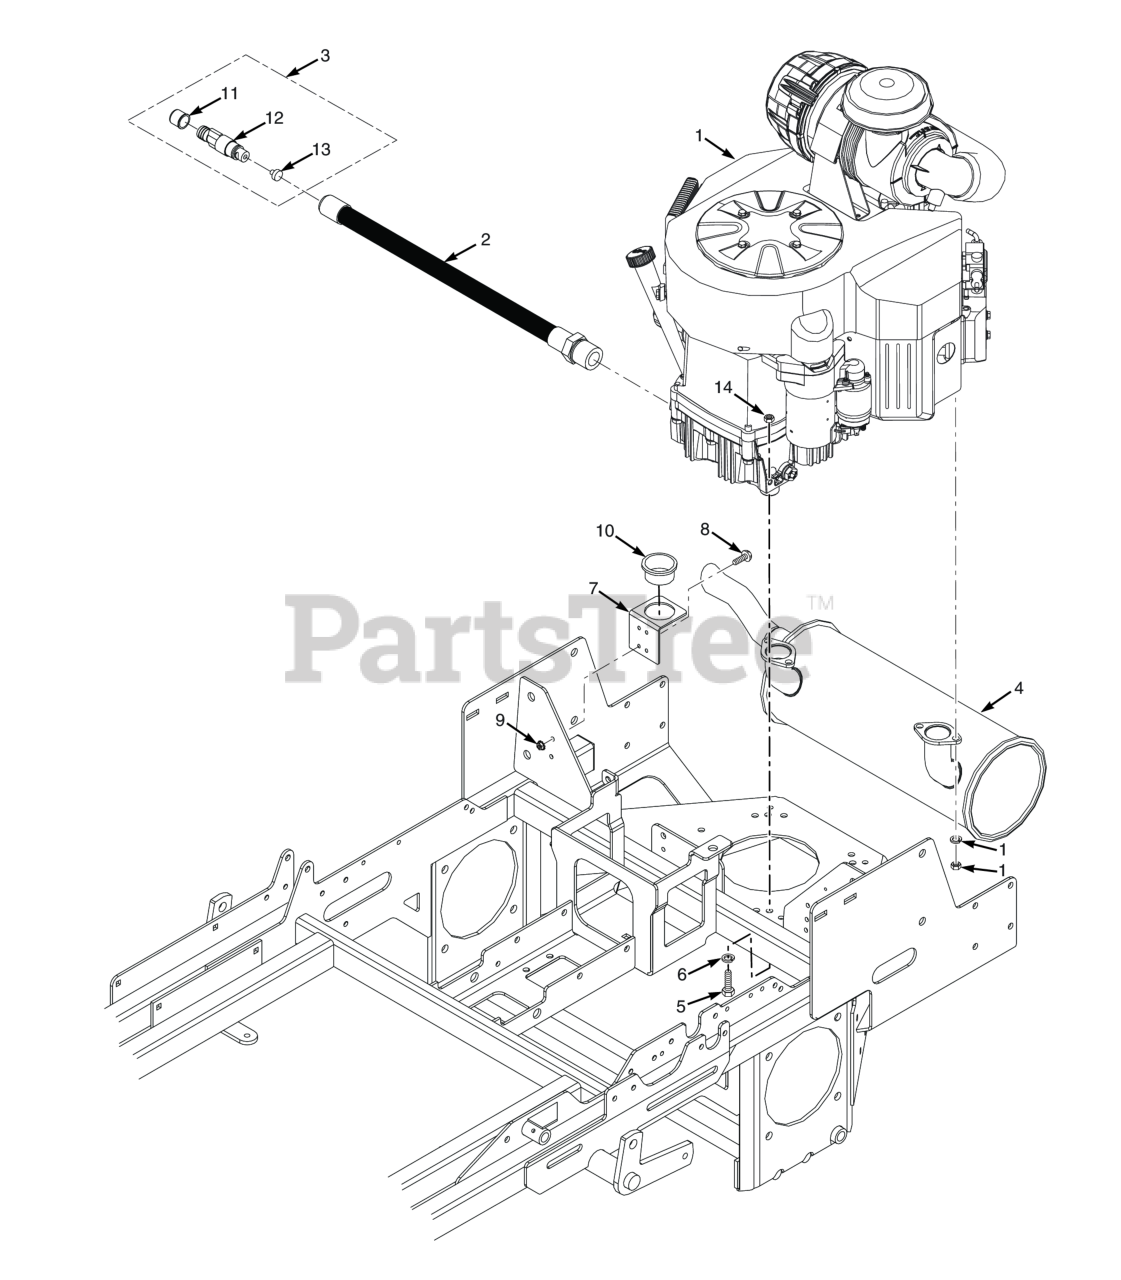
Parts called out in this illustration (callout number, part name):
1	Engine, Briggs & Stratton 37 BV-EFI (61E8770002J1)
2	Hose Assembly, Engine Oil Drain - Kawasaki FS/FX
3	Valve Assembly, Oil Drain
4	Muffler, Kawasaki - FX921
5	Bolt, Hex Head 3/8-16 x 1-1/4", Kawasaki FX / FT & FT-EFI
6	Lockwasher, 3/8" Spring, Kawasaki FX / FT & FT-EFI / B&S 32BV
7	Bracket, Oil Drain Hose
8	SCR,#8-32 X .625 HX WSHR HD SLOTTED
9	Nut, Elastic Stop #8-32
10	Bushing, Thick Panel Snap
11	O-Ring
12	O-Ring
14	Nut, Flanged Top Lock 3/8-16
